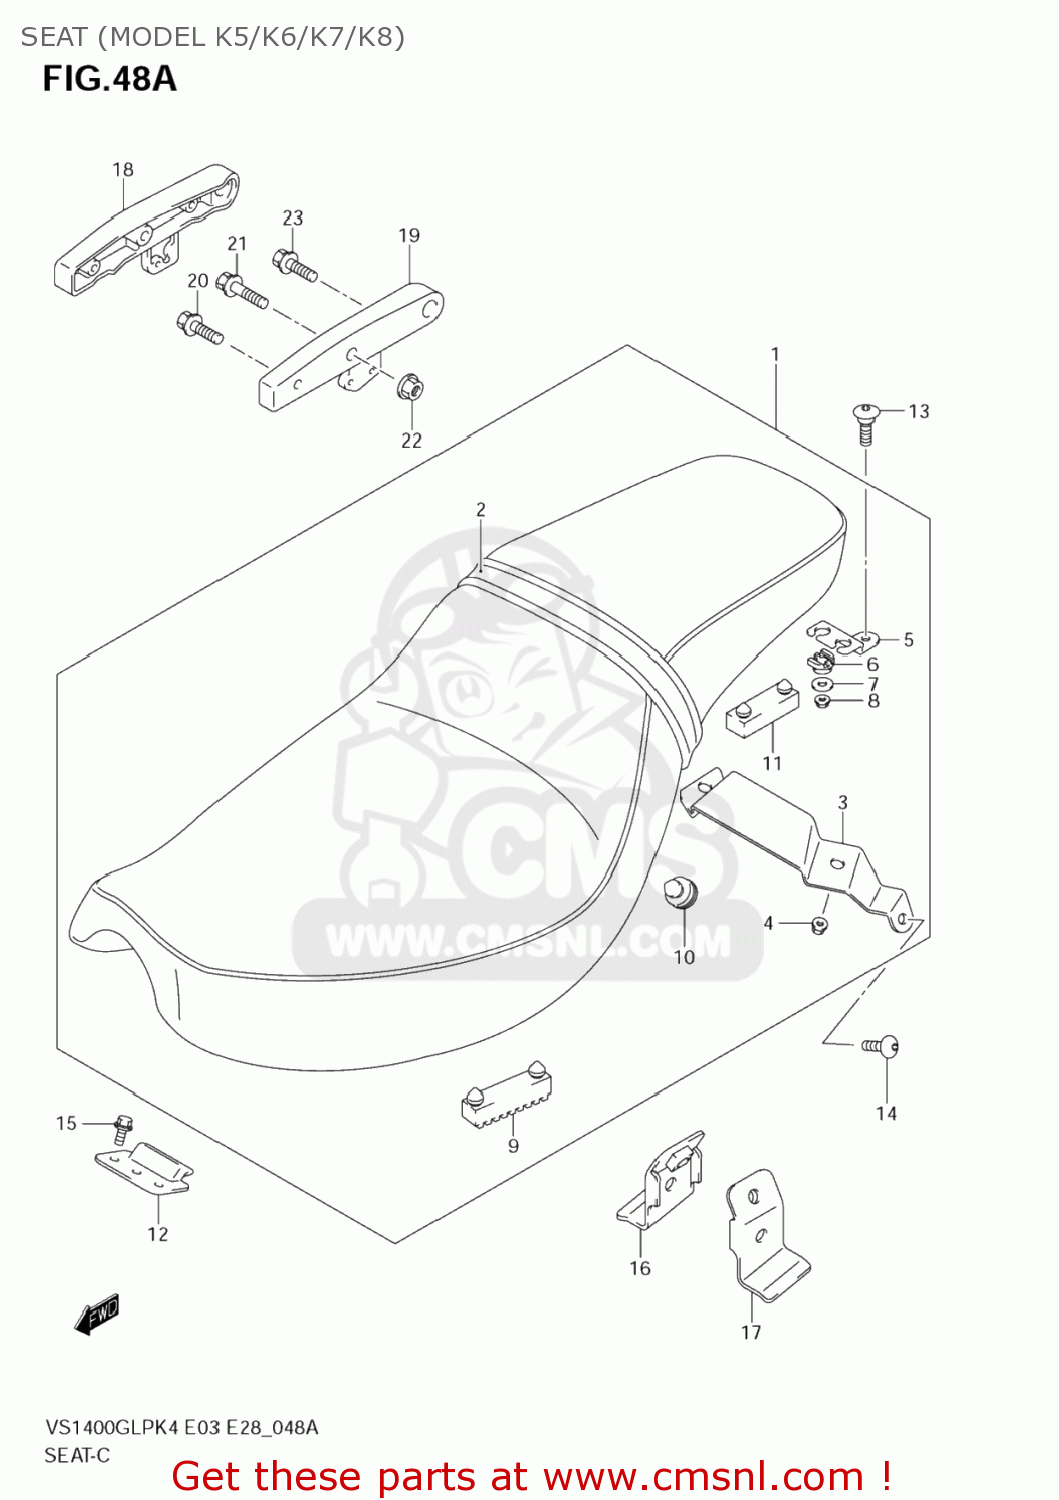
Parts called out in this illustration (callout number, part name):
1	SEAT ASSY
2	BAND ASSY
3	BRACKET,BAND
4	NUT
5	BRACKET,SEAT RR
6	CUSHION
7	WASHER(6.5X20X1.6)
8	NUT
9	CUSHION,SEAT
10	CUSHION,FR
11	CUSHION,SEAT
12	BRACKET,SEAT FR
13	SCREW(6X16)
14	BOLT(6X12)
15	BOLT
16	BRACKET,SEAT CTR,R
17	BRACKET,SEAT CTR,L
18	HANDLE,PILLION RIDER,R
19	HANDLE,PILLION RIDER,L
20	BOLT
21	BOLT
22	NUT
23	BOLT
